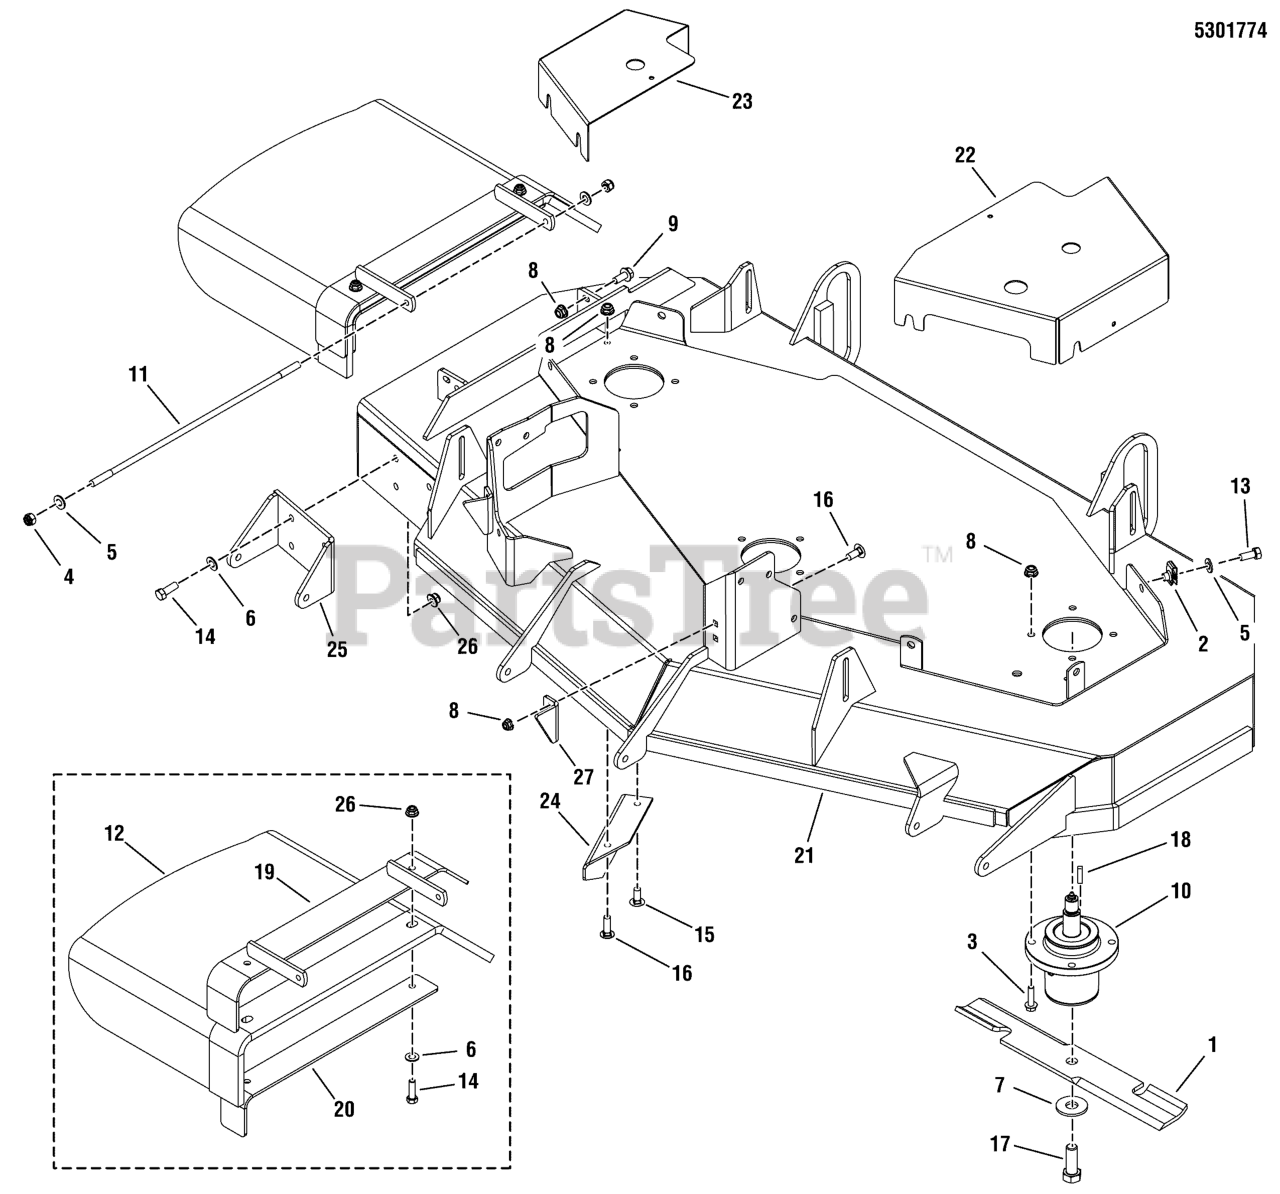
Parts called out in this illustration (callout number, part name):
1	BLADE, 18 X .25 X 2.5, 1 X 3.5 (SET OF 3)
2	BODY CLIP, 5/16-18-7GA MATERIAL
3	BOLT, 5/16-18 X 1 1/4 FLANGE
4	NUT, 5/16-24 HEX NYLON LOCK
5	WASHER, 5/16" SAE
6	WASHER, 3/8 SAE
7	WASHER, BLADE BOLT, 9/16" F436, CZ
8	NUT, 5/16-18 HEX NYLOCK FLANGE
9	BOLT, 5/16-18 X 3/4 GD5
10	ASSM, SPINDLE, LOW PROFILE
11	ROD MOUNT, CHUTE 61"
12	CHUTE, DISCHARGE, RUBBER 61/72"
13	BOLT, 5/16-18 X 3/4 GD5
14	BOLT, 3/8-16 X 1-1/4" GD5 CZ
15	BOLT, 5/16-18 X 3/4, CARRIAGE
16	BOLT, 5/16-18 X 1, CARRIAGE
17	BOLT, 5/8-11 X 1-3/4 GD8
18	KEY, 1/4 SQ X 1
19	WELD, FRAME, CHUTE, 52 - RED
20	SUPPORT, DISCHARGE CHUTE - BLK
21	DECK SHELL W/ DECALS, 52, S75X
22	GUARD, LH PULLEY, EVO 52 - RED
23	GUARD, 52 MOWER DECK, RH - RED
24	PLATE, DEFLECTOR - BLK
25	PLATE, BRACKET, ANTI SCALP - RED
26	NUT, 3/8-16 HEX NYLOCK FLANGE
27	PLATE, DECK STOP, EVO 48
